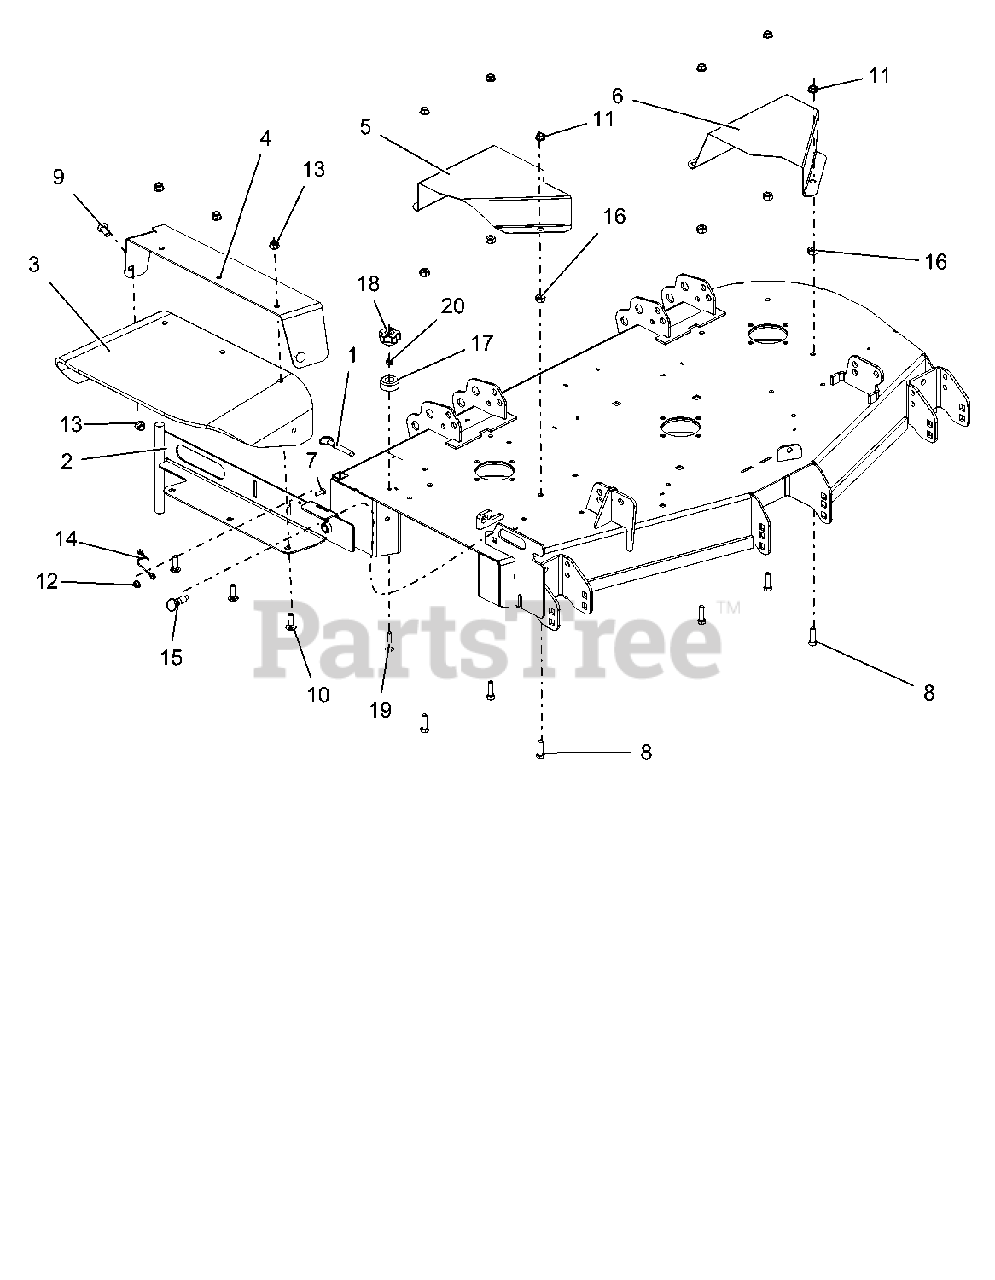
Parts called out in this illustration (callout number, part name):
1	PIN, SPRING BALL .375 OD X 1.50
2	WLDMT, DISCHARGE CHUTE 44"-48" (RED)
3	CHUTE, RUBBER DISCHARGE
4	SUPPORT, CHUTE MOUNTING BRKT
5	GUARD, DECK 44"-52" RH (RED)
6	GUARD, DECK 44-52" LH (RED)
7	BLT-HEX .25-20X.75 GR5 YWZC
8	BLT-HEX .38-16X1.25 GR5 YWZC
9	BLT-RDHDSQNK .38-16X1.00 G5 YWZC
10	BLT-RDHDSQNK .38-16X1.25 G5 YWZC
11	@NUT-SPNLK-FLG .375-16 YWZC
12	NUT, LK-TOP-FLG .25-20 YWZC
13	NUT-LK-NYL-FLG .38-16 YWZC
14	CABLE, 6.0 LANYARD, NYLON
15	PULL PIN,.50-13THDX.310 PLNGR
16	NUT-HEAVY HEX .38-16 YWZC
17	BUMPER, RECESSED 1.50 X .63 W/.31 HOLE
18	KNOB, CLAMPING
19	BLT-RDHDSQNK .31-18X1.50 G5 YWZC
20	NUT-LK-CTR .31-18 YWZC
